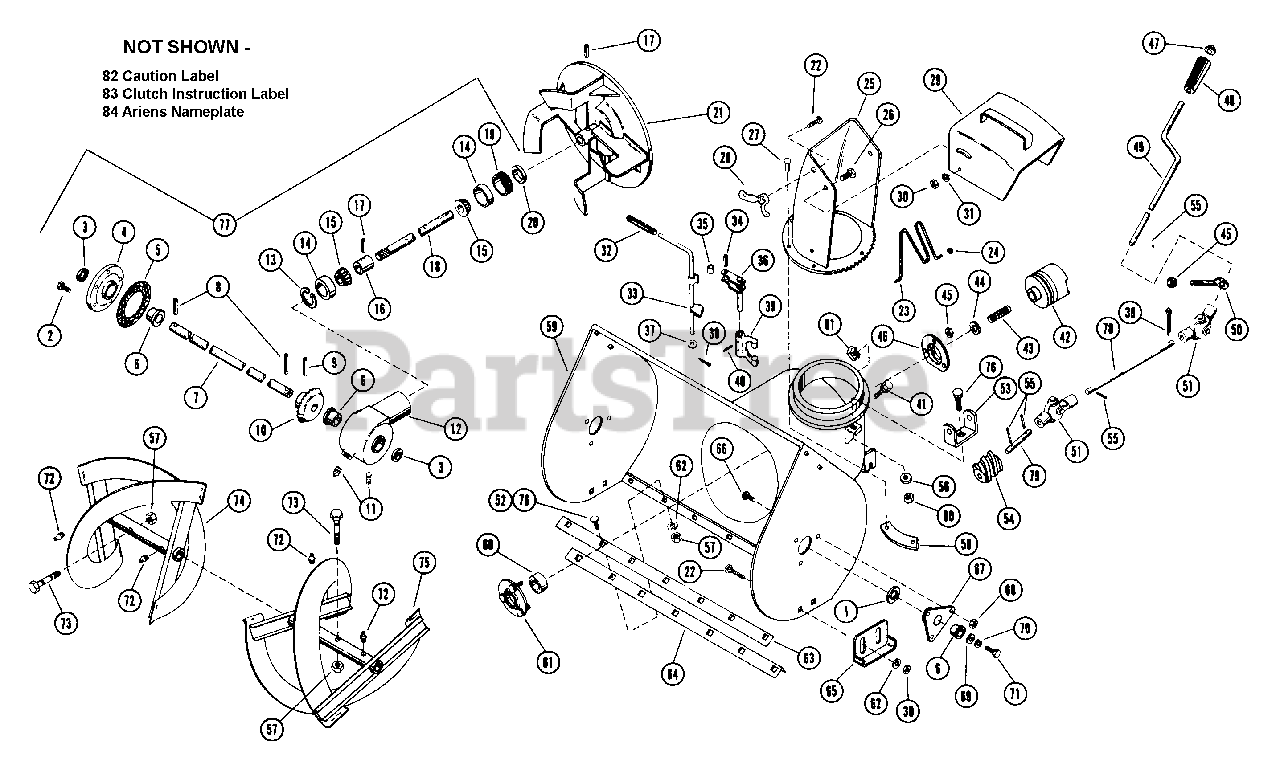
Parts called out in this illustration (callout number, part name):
1	WSHR-FL-STL 1.010X1.505X.062PL
2	BLT-SERHFWH .25-20X.75 PL
3	SEAL 1.000X1.312X.150
4	GEAR CASE FLANGE
6	BSHG-FLG 1.000X1.12X.62X1.50BR
7	FRONT GEAR SHAFT
8	PIN-ROLL .188X1.50
9	PIN-ROLL .313X1.38
10	HELICON GEAR - 41 TOOTH
11	PIPE PLUG
12	CASE, GEAR - C.I.
13	RG-RTNG INT 1.781 HSG X.062
14	BRG-CUP 1.781X.475
15	BRG-CONE .750X.61
16	BEARING SPACER
17	PIN-ROLL .250X1.25
18	HELICON PINION SHAFT
19	ADJUSTMENT PLUG
20	SEAL .750X1.499X.225
22	BLT-RDHDSQNK .38-16X.75 SHT PL
23	SAFETY WIRE
24	FASTENER
25	DISCHARGE CHUTE
26	BLT-HEX .38-16X.75 PL GR2
27	SCR-TAP 10-24X.375 CRPH 1A
28	WING NUT
29	DEFLECTOR CHUTE
30	NUT-LK-CTR .375-16 GR A PL
31	WSHR-LK .375X.115 HVY PL
33	FORK CAM
34	PIN-ROLL .313X1.25
36	FORK SHAFT
37	WAVE WASHER .406X.750X.063FH
38	PIN-COTR .12X1.0 PL
39	CLUTCH FORK
40	PIN-ROLL .188X1.00
41	BLT-SCRHFWH .38-16X.75 PL
42	JAW CLUTCH
43	SG-COMP .105X1.35X1.984
44	WSHR-FL-STL .755X1.375X.062 PL
45	NUT-LK-CTR .250-20 PL
46	BEARING FLANGE
47	CAP, 3/8 ROD YWZC
48	GRIP
49	CHUTE CONTROL CRANK
50	ROD HANGER EYEBOLT
51	UNIVERSAL JOINT ASSEMBLY
52	BLT-RDHDSQNK .312-18X.62 PL
53	WORM CLEVIS
54	WORM GEAR
55	PIN-ROLL .125X.75
56	WSHR-LK .313X.062
57	NUT-LK .312-18 GR A PL
58	CHUTE CLAMP
59	BLOWER HOUSING 24 IN
59	BLOWER HOUSING 32 IN
60	BRG-BALL .750X1.750X.50
61	BEARING FLANGE
62	WSHR-FL-STL .38X.875X.083 PL
63	SCRAPER BLADE
63	SCRAPER BLADE 24"
64	REINFORCEMENT ANGLE
65	RUNNER
66	SCR-SLTR-SERNK .25-20X.62 PL
67	BEARING SUPPORT
68	NUT-LK-FLG .250-20 PL
69	WSHR-FL-STL .511X1.441X.125 PL
70	WSHR-LK .500X.151 HVY PL
71	BLT-HEX .50-13X1.00 PL GR2
72	HYDRAULIC DRIVE FITTING
73	SHEAR BOLT YWZC
74	RAKE, R.H. - 32"
74	RAKE, RIGHT-24"(1ID X 15.88OD)
75	RAKE, L.H. - 32"
75	RAKE, LEFT-24"(1"ID X 15.88OD)
76	BLT-RDHDSQNK .31-18X.75 GR5 PL
77	GEAR CASE - C.I.
77	GEAR CASE ASSEMBLY
78	ROD
79	WORM SHAFT
80	NUT-HEX .312-18
81	NUT-RETNR .38-16 TINRMAN
